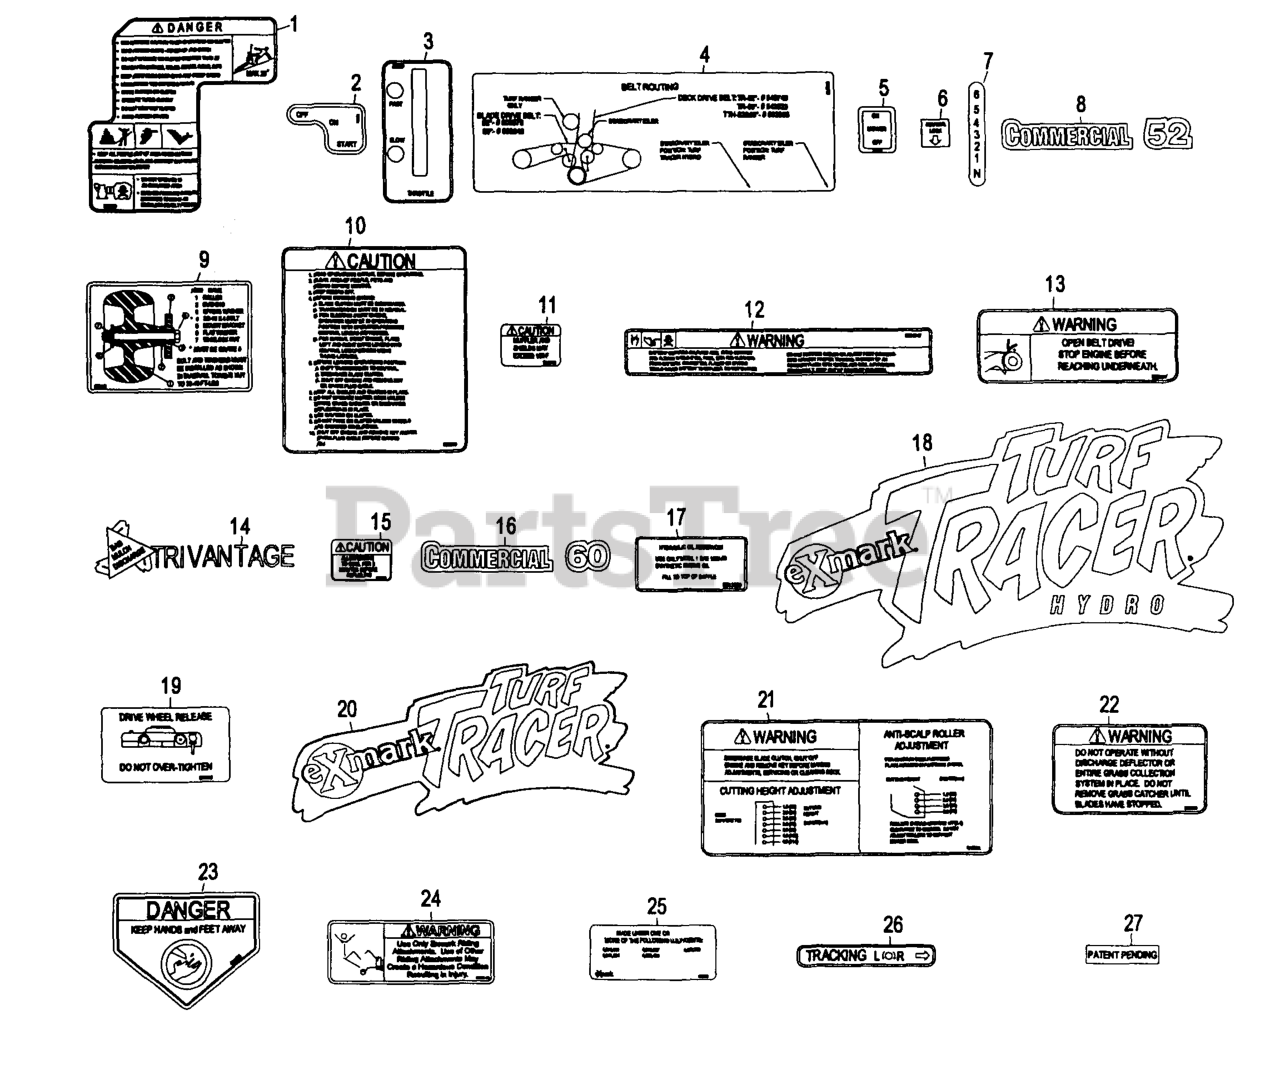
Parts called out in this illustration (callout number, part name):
4	DECAL,BELT ROUTING
5	DECAL-MOWER SWITCH
6	DECAL,NEUTRAL LOCK
7	DECAL - SHIFTER
8	DECAL,COMMERCIAL 52
9	DECAL,ROLLER MOUNTING
12	DECAL-BATTERY
13	DECAL,BELT DRIVE
16	DECAL,COMMERCIAL 60
17	DECAL,HYD TANK
19	DECAL,DRIVE RELEASE
22	DECAL-WARNING, DISCHARGE
23	DECAL-DANGER
24	DECAL,SULKY WARNING
26	DECAL,TRACKING ADJUST
27	Decal, Patent Pending
